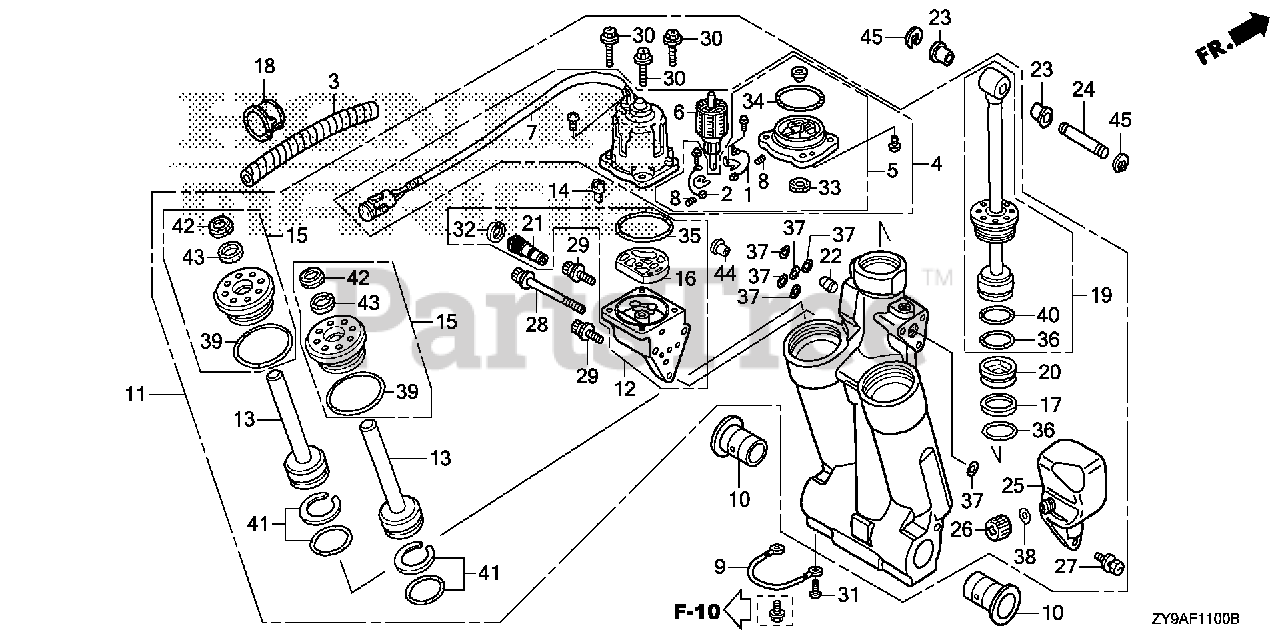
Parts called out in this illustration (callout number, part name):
1	BREAKER ASSY.
2	BRUSH ASSY.
3	TUBE, SPIRAL (12X14.6)
4	MOTOR ASSY., POWER TILT
5	BRACKET ASSY.
6	ARMATURE
7	YOKE ASSY.
8	SPRING, MOTOR
9	WIRE, LEAD (1.5X116MM)
10	BUSH, SWIVEL CASE
11	TRIM-TILT ASSY., POWER
11	TRIM-TILT ASSY., POWER (NOT AVAILABLE)
12	PUMP ASSY.
13	ROD, PISTON (B)
14	JOINT, DRIVE
15	GUIDE, ROD
16	FILTER (B)
17	RING, BACK-UP
18	BUSH, MOTOR CODE
19	ROD, PISTON
20	PISTON, FREE
21	VALVE, MANUAL
22	VALVE, RESERVOIR
23	BUSH, CYLINDER (LOWER)
24	PIN, CYLINDER (UPPER)
25	TANK, OIL
26	CAP, OIL TANK
27	BOLT, RECESSED
28	BOLT A, SOCKET
29	BOLT B, SOCKET
30	BOLT, HEX.
31	SCREW, PAN (6X8)
32	CIRCLIP (INNER)
34	O-RING (2.0X70.5)
35	O-RING (1.8X69.6)
36	O-RING (3.5X38.7)
37	O-RING (1.8X7.7)
37	O-RING (1.68X7.25)
38	O-RING (1.9X11)
39	O-RING (3.5X35.7)
40	O-RING (3.5X41.7)
41	O-RING SET (3.5X31.7)
42	SEAL, WATER
44	COLLAR, ORIFICE
45	E-RING (15MM)
